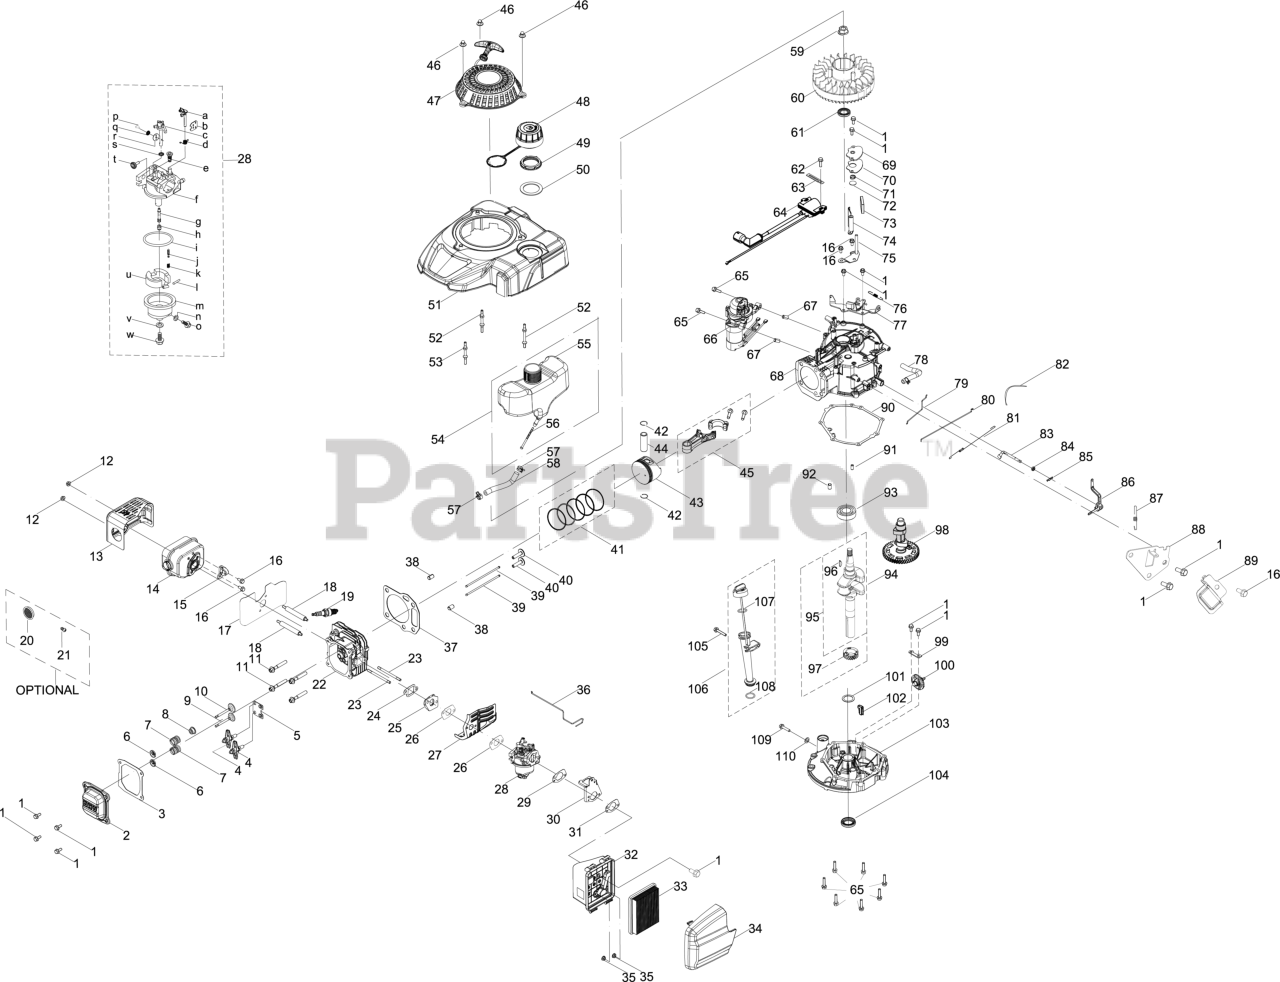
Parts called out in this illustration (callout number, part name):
1	BOLT M6-1 x 14 GR8.8
2	VALVE COVER
3	VALVE COVER GASKET
4	ROCKER ARM
5	PUSH ROD GUIDE
6	VALVE RETURN SPRING
7	VALVE SPRING
8	INTAKE VALVE SEAL
9	EXHAUST VALVE
10	INTAKE VALVE
11	BOLT-M8 x 54
12	HEX NUT
13	MUFFLER SHIELD
14	MUFFLER ASSEMBLY
15	CHOKE TEMP CONTROL THERMOSTAT
16	BOLT M6-1 x 12 GR8.8
17	MUFFLER GASKET
18	STUD M6-1 x 95
19	SPARK PLUG (F5RTC/RN11YC4/BPR5ES)
19	Cub Cadet SPARK PLUG-F5RTC
19	Genuine Factory Parts SPARK PLUG (14437)
20	SPARK ARRESTOR
21	SCREW M3.5 x 9.5
22	CYLINDER HEAD
23	STUD M6 x 90
24	CARBURETOR INSULATOR GASKET
25	CARBURETOR INSULATOR
26	CARBURETOR GASKET
27	CARBURETOR HEAT SHIELD
28	CARBURETOR
29	AIR FILTER BRACKET GASKET
30	AIR FILTER BRACKET
31	AIR FILTER BASE GASKET
32	AIR FILTER BASE
33	AIR FILTER
34	AIR FILTER COVER
35	HEX NUT
36	CHOKE TEMP CONTROL LINKAGE
37	CYLINDER HEAD GASKET
38	PIN (10MMx16MM)
39	PUSH ROD
41	PISTON RING SET
42	WRIST PIN CLIP
43	PISTION
44	PISTON PIN
45	CONNECTING ROD ASSEMBLY
46	ACORN NUT M6-1
47	RECOIL STARTER ASSEMBLY
48	FUEL CAP W/TETHER
49	FUEL TANK NUT
50	FUEL TANK GROMMET
51	ENGINE SHROUD W/O IGNITION SWITCH
52	STARTER/SHROUD REAR STUD
53	STARTER/SHROUD FRONT STUD
55	FUEL TANK
56	FUEL FILTER
57	CARBURETOR HOSE CLAMP
58	FUEL HOSE
59	FLYWHEEL NUT M14-1.5
60	FLYWHEEL
61	UPPER CRANKSHAFT SEAL
62	BOLT M6-1 x 20 GR8.8
63	FLEXIBLE CLAMP
64	IGNITION COIL ASSEMBLY
65	BOLT-M6-1 x 28 GR8.8
66	ELECTRIC STARTER ASSEMBLY
67	DOWEL PIN
68	CRANKCASE
69	BREATHER COVER PLATE
70	BREATHER GASKET
71	BREATHER VALVE SPRING
72	BREATHER VALVE
73	BREATHER SCREEN
74	AIR VANE
75	AIR VANE BRACKET
76	ENGINE BRAKE SPRING
77	ENGINE BRAKE ASSEMBLY
78	BREATHER HOSE ASSEMBLY
79	CHOKE LINKAGE
80	THROTTLE LINKAGE
81	THROTTLE LINKAGE SPRING
82	CABLE TIE 3x150
83	GOVERNOR ARM SHAFT
84	OIL SEAL
85	COTTER PIN
86	GOVERNOR ARM ASSEMBLY
87	GOVERNOR SPRING
88	COMPONENT BRACKET
89	GOVERNOR SHIELD
90	CRANKCASE COVER GASKET
91	DOWEL PIN 7 X 14
92	DOWEL PIN 9 X 14
93	BEARING
94	CRANKSHAFT ASSEMBLY
95	CRANKSHAFT
96	WOODRUFF KEY
98	CAMSHAFT
99	GOVERNOR GEAR MOUNTING PLATE
100	GEAR GOVERNOR
101	THRUST WASHER
102	OIL RETURN SEAL
103	CRANKCASE COVER
104	LOWER CRANKSHAFT SEAL
105	BOLT M6-1 x 35 GR8.8
106	OIL DIPSTICK ASSEMBLY
109	OIL DRAIN PLUG
110	FLAT WASHER
S	CARB SHAFT GASKET
